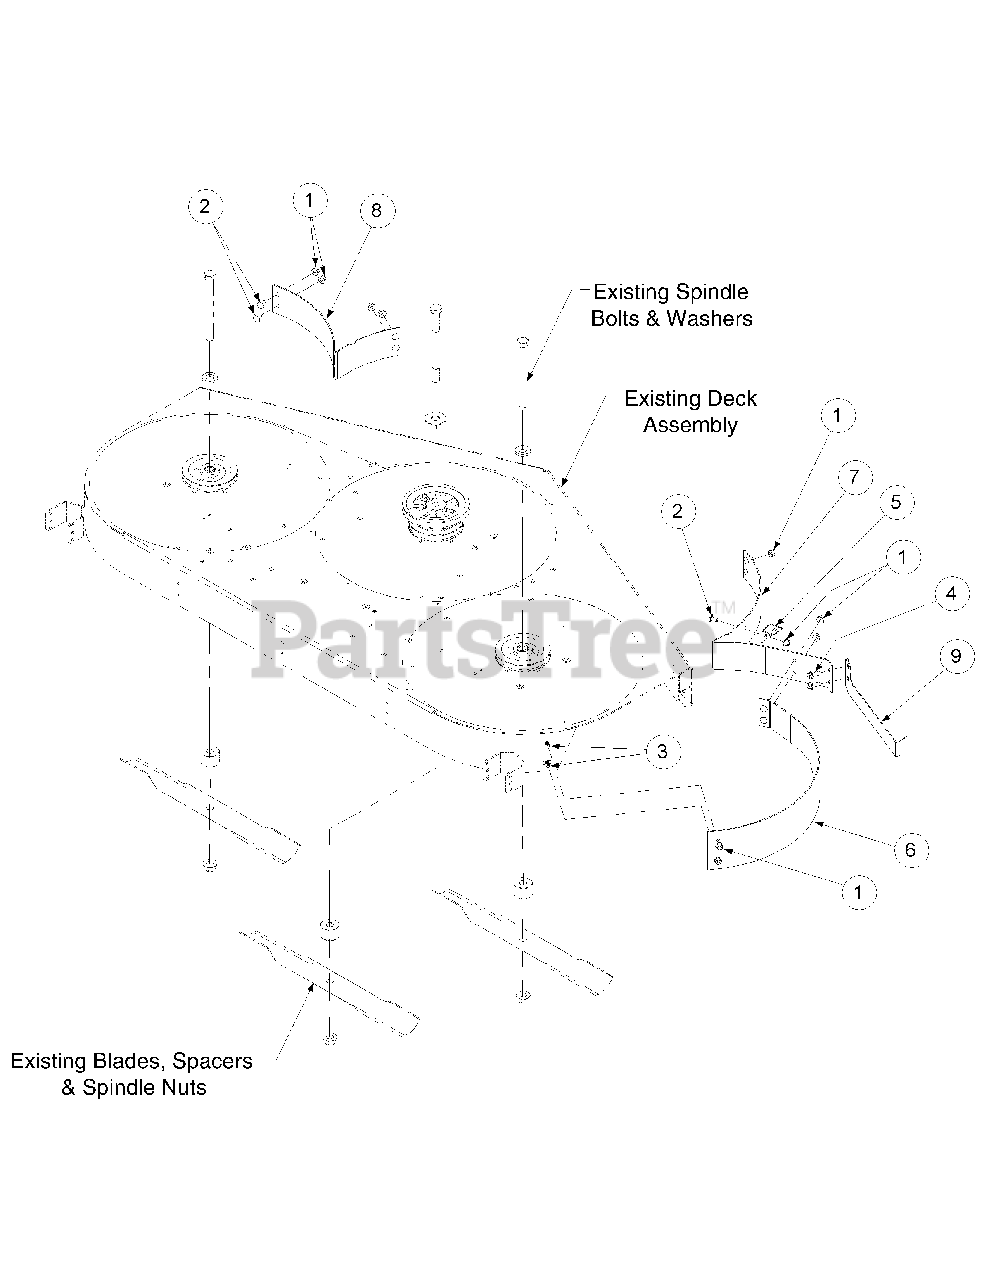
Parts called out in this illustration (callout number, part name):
1	Hex Nut, 3/8-16 Flange Lock
2	Carriage Bolt, 3/8-16 x .75
3	Carriage Bolt, 3/8-16 x 1.00
4	Self Tapping Screws, 3/8-16 x .875
5	Mulching Bracket Assembly
6	Mulching Baffle, RH
7	Mulching Baffle, Center
8	Mulching Baffle, LH
9	Deflector Baffle
